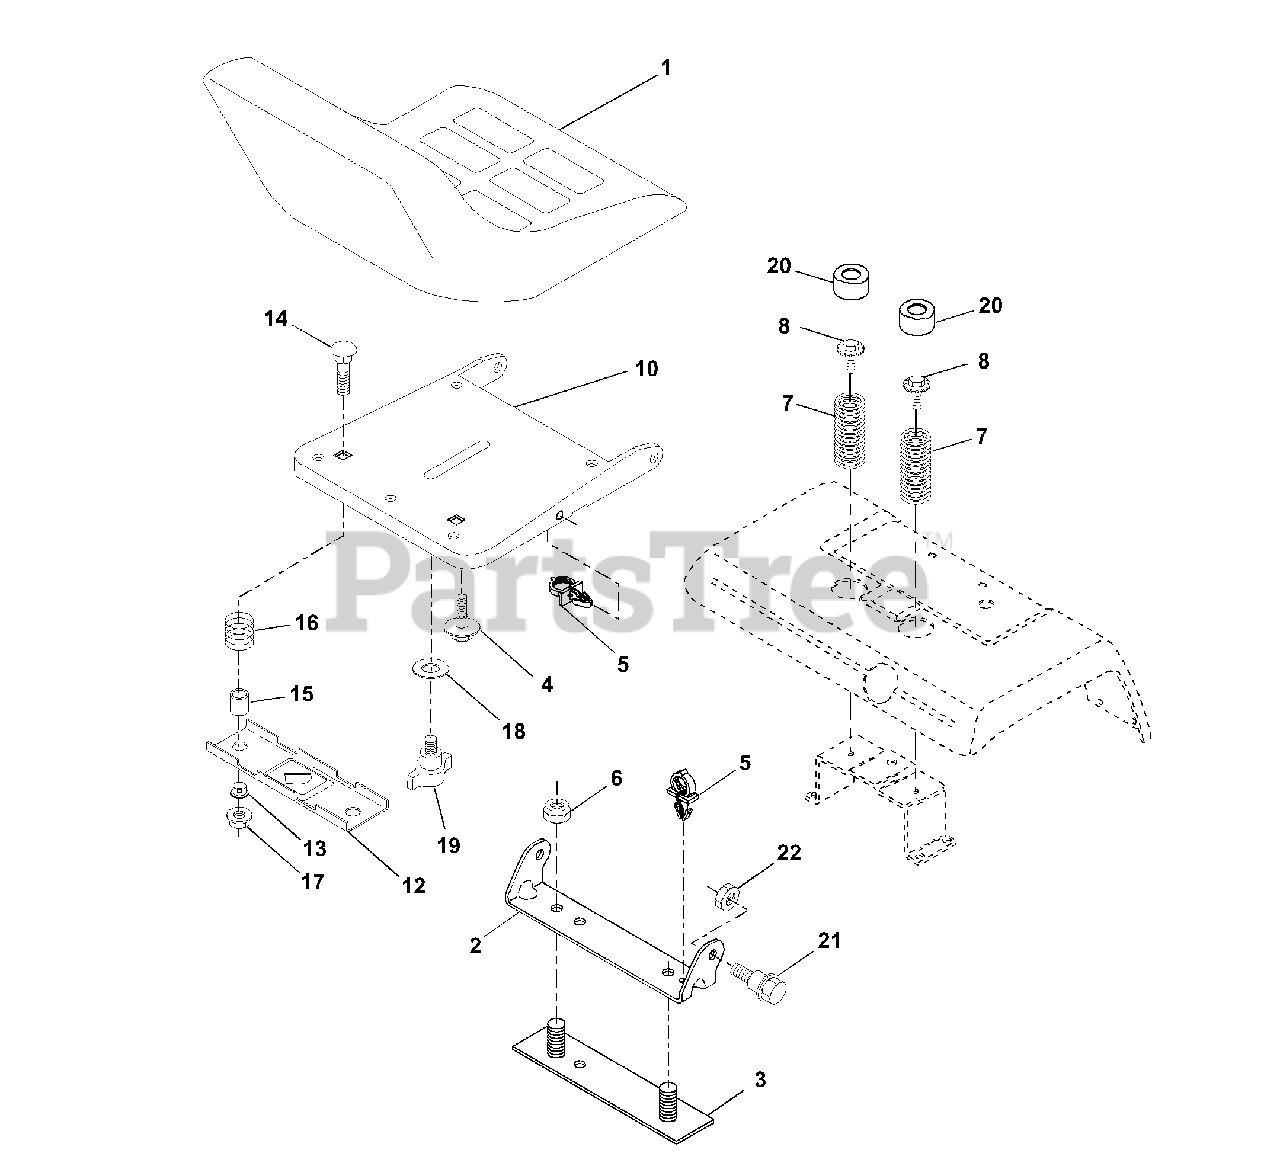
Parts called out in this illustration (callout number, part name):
1	Seat
2	Bracket, Pivot Seat
3	Strap, Fender Asm.
4	Bolt, Shoulder 5/16-18 x .62
5	Clip, Push-In Hinged
6	Nut, Crownlock 3/8-16
7	Spring, Seat Cprsn.
8	Bolt 5/16-18 UNC x 3/4 w/Sems
10	Pan, Seat
12	Bracket, Mounting Switch
13	Bushing, Snap
14	Bolt, Carriage 1/4-20 x 1-1/2
15	Spacer, Split
16	Spring, Cprsn.
17	Nut, Lock 1/4 Lg. Flg. Gr. 5
18	Washer 17/32 x 1-3/16 x 12 Ga.
19	Knob, Seat
20	Cap, Spring Seat Blk
21	Bolt 5/16-18
22	Nut, Crownlock 5/16-18
